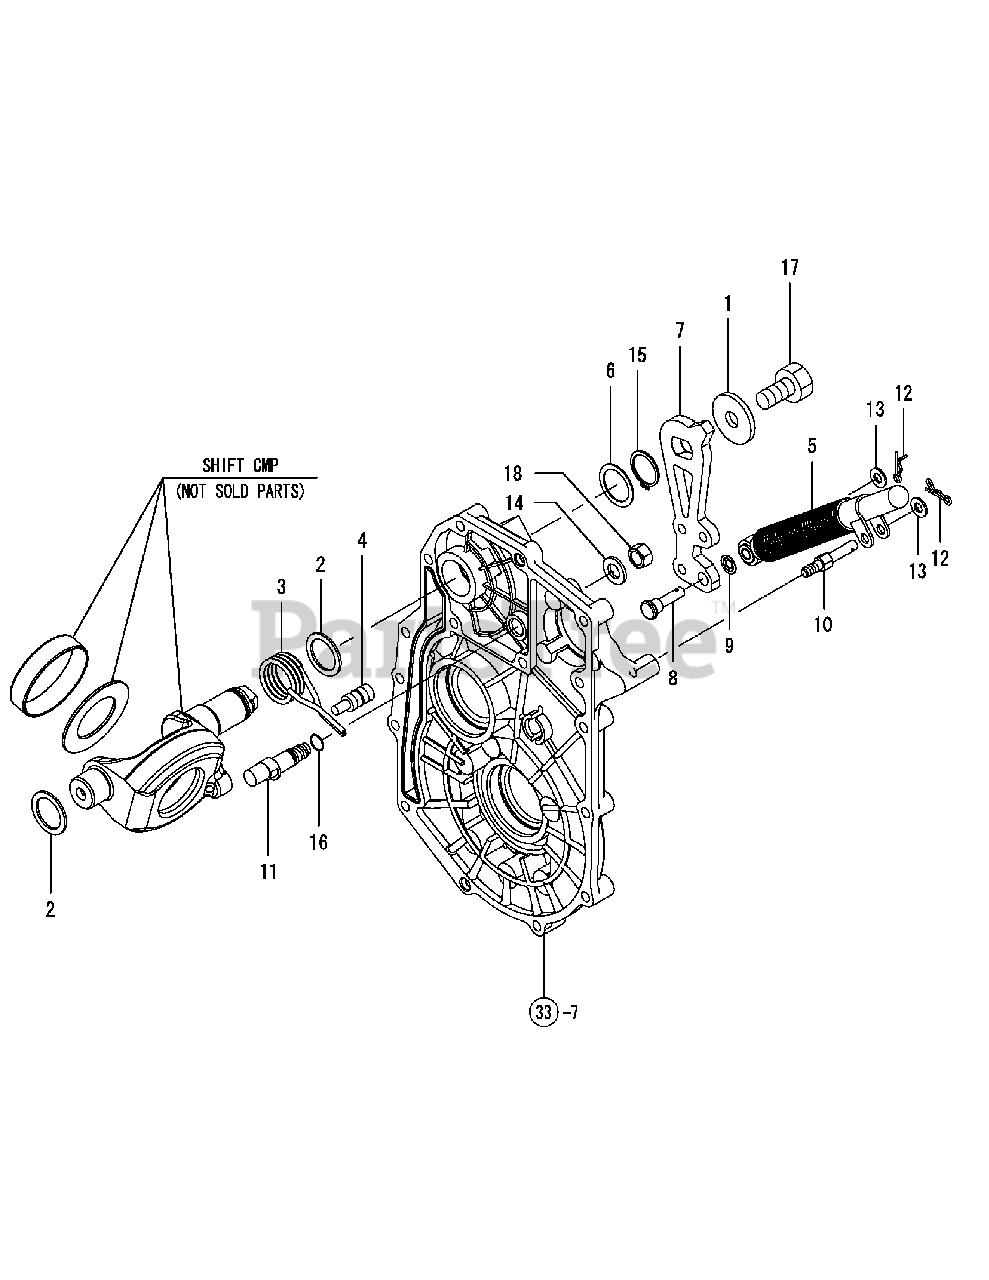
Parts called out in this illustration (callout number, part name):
1	WASHER 44X14X4.5
5	ABSORBER, SHOCK
6	WASHER 29X35X1
8	PIN, CONTROL ARM
12	PIN 8, COME-OFF SNAP
13	WASHER 8, POLISHED
14	WASHER 12, POLISHED
16	O-RING 1A P-10A
17	BOLT M14X 30 PLATED
18	LOCK NUT M12 PLATED
